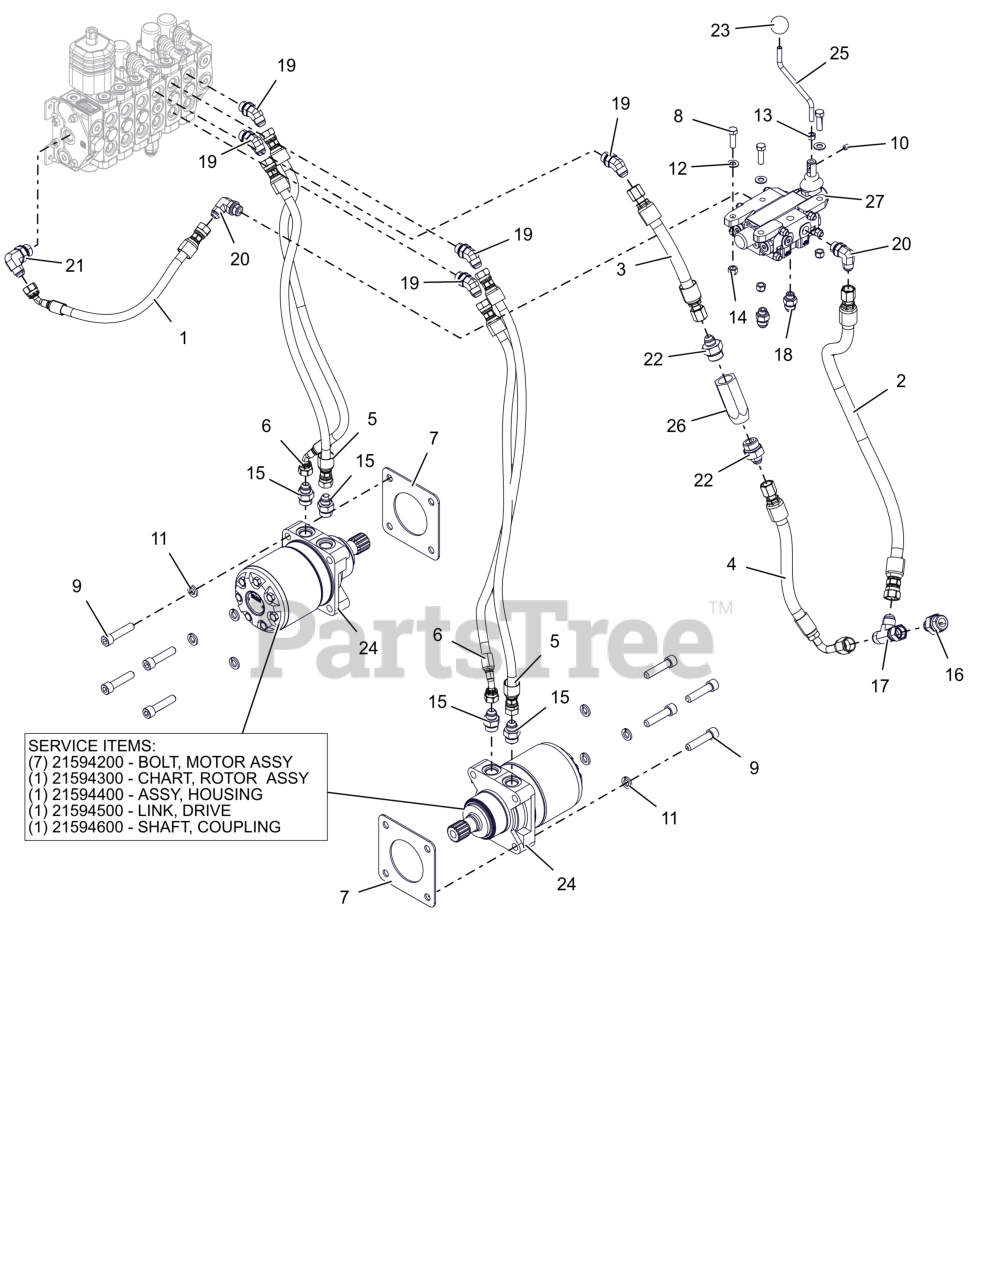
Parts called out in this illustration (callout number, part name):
1	HOSE, HYD .375" X 17.75" LG
2	HOSE, HYD .500" X 31.50" LG
3	HOSE, HYD .500" X 10.50" LG
4	HOSE, HYD .500" X 16.00" LG
5	HOSE, HYD FJIC-8-6 FJIC-8-6 32
6	HOSE, HYD 45FJIC-8-6 FJIC-8-6 31
7	GASKET, MOTOR HYD
8	BLT, HEX .38-16X1.25 G5 ZCC
9	SCR, SKH .500-13X2.250 GR8 ZCC
10	SCR-SET, 1.50-6X1.500 CUP
11	WSHR,LK-REG 0.502 X 0.125 ZCC
12	WSHR,FLT .406X.812X.065 ZCC
13	NUT, HEX M8-1.25 G8.8 ZCC
14	NUT,NYL .38-16 G5 ZCC
15	FITTING, HYDRAULIC 6400 8-10
16	FITTING, HYDRAULIC 6400 10-12
17	FITTING, HYDRAULIC 6602 10-10-10
18	FITTING, HYDRAULIC 6400 8-6
19	FITTING, HYDRAULIC - 6802 8-8
20	FITTING, HYDRAULIC 6801 8-8
21	FITTING, HYDRAULIC - 6801 8-10
22	ADAPTER, 8MJ-12MB
23	KNOB, BALL -.312" PRESS ON
24	MOTOR, HYDRAULIC
24	BOLT, MOTOR ASSY
24	CHART, ROTOR ASSY
24	ASSY, HOUSING
24	LINK, DRIVE
24	SHAFT, COUPLING
25	LEVER, AUXILIARY
26	VALVE, HYD -CHECK 72 PSI
27	VALVE, CONTROL - AUX
